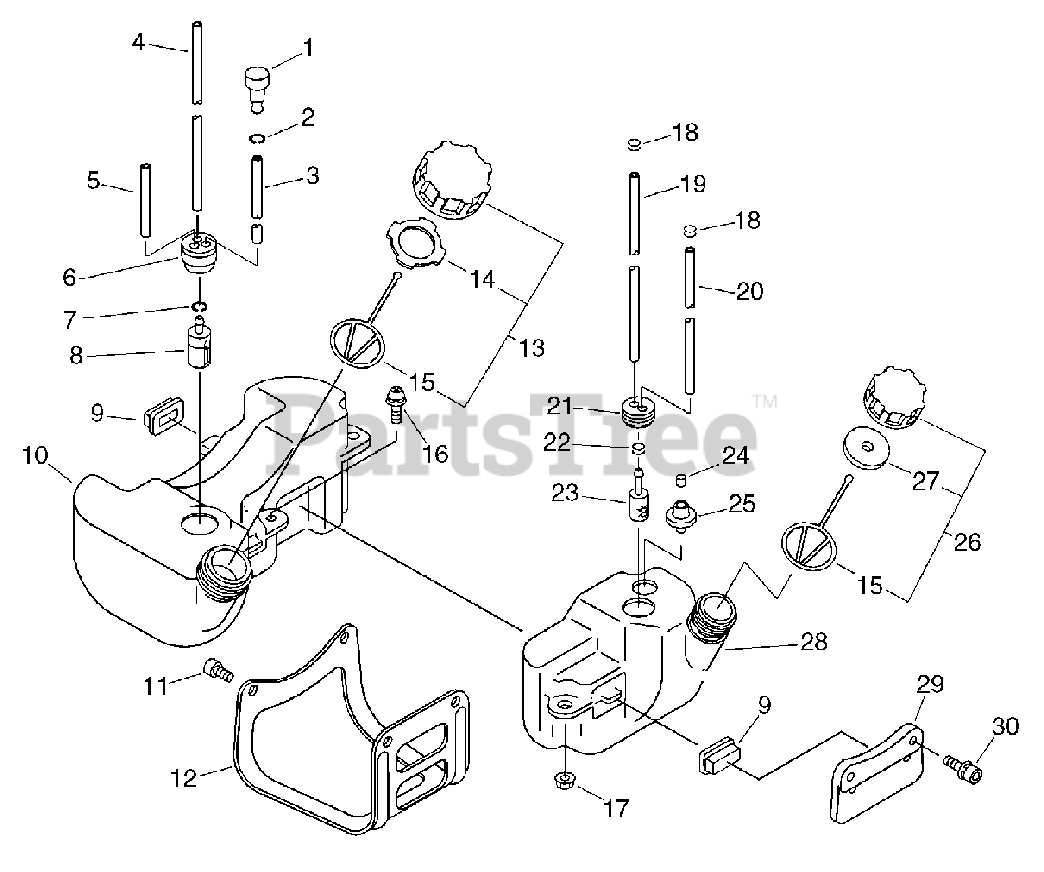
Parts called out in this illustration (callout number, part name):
1	VENT ASSY
3	PIPE 3×6×90 BLACK
3	PIPE, FUEL 3×5×90 BLACK
4	PIPE, FUEL 3×6×170
5	PIPE, FUEL 3×6×60 CLEAR
6	GROMMET, FUEL
7	CLIP 6.5 MM
8	FILTER, FUEL
9	CUSHION, FUEL TANK
10	TANK, FUEL
11	BOLT 5×12
13	CAP ASSY
14	GASKET, FUEL CAP
15	CONNECTOR, CAP
16	SCREW - 5×18
17	NUT, FLANGE M5
19	PIPE 2×4×180
20	PIPE 2×4×100
21	GROMMET, FUEL
23	FILTER, OIL
24	FILTER, CHECK VALVE
25	VENT ASSY
26	CAP ASSY
27	GASKET, CAP
28	TANK, OIL
29	BRACKET, FUEL TANK
30	BOLT 5×20
